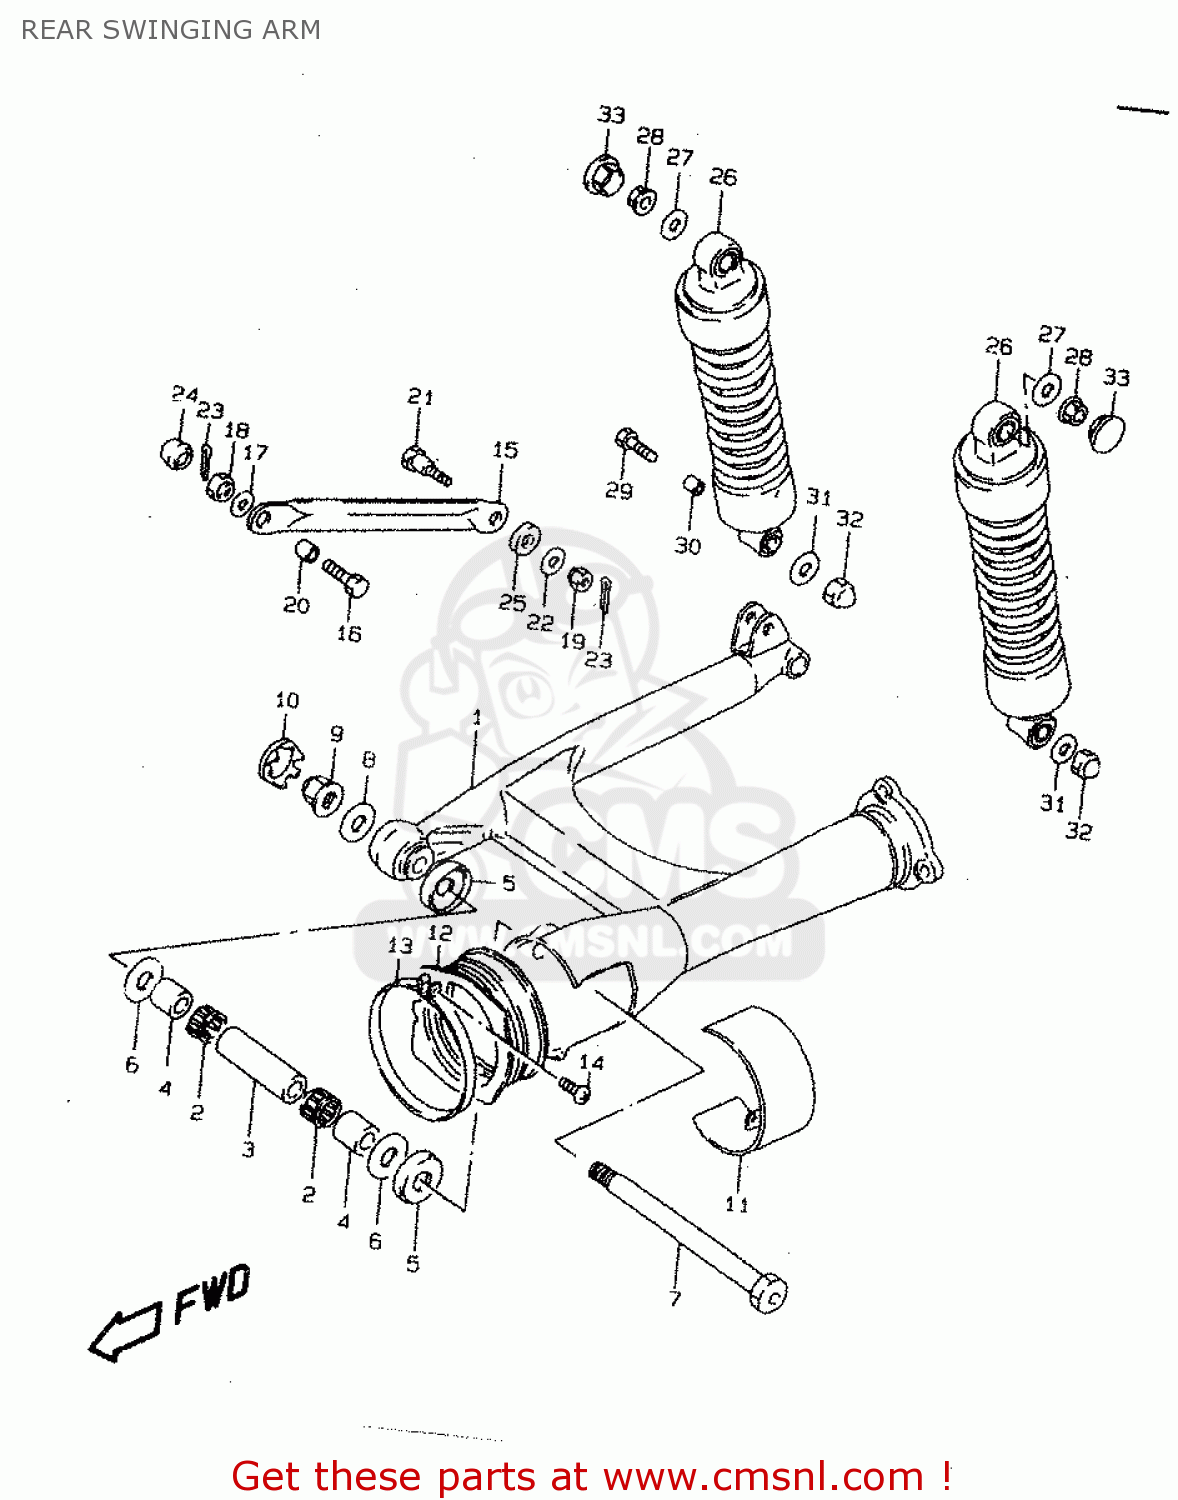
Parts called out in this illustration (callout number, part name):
1	SWINGINGARM,RR
2	BEARING(22X29X20)
3	SPACER,RR SWGARM PIVOT
4	SPACER,RR SWGARM PIVOT
5	SEAL,RR SWGARM PIVOT DUST
6	WASHER
7	SAHFT,RR SWGARM PIVOT
8	WASHER(17X30X3)
9	NUT 16MM
10	CAP,RR SWINGING ARM PIVOT,R
11	COVER,RR SWGARM PIVOT,L
12	BOOT,PROPELLER SHAFT
13	CLAMP
14	SCREW
15	TORQUELINK,RR
16	BOLT(10X28)
17	WASHER (10X20X2.3)
18	NUT
19	NUT
20	SPACER(10.2X14X9.6)
21	BOLT(10X41)
22	WASHER (10X20X2.3)
23	PIN 16X20
24	CAP
25	CUSHION
26	ABSORBER ASSY,RR SHOCK
27	WASHER(10.5X20X2.3)
28	NUT
29	BOLT(10X39)
30	SPACER(10.2X14X20.7)
31	WASHER (10.5X24X2.3)
32	NUT
33	CAP,FRAME HANDLE GRIP
